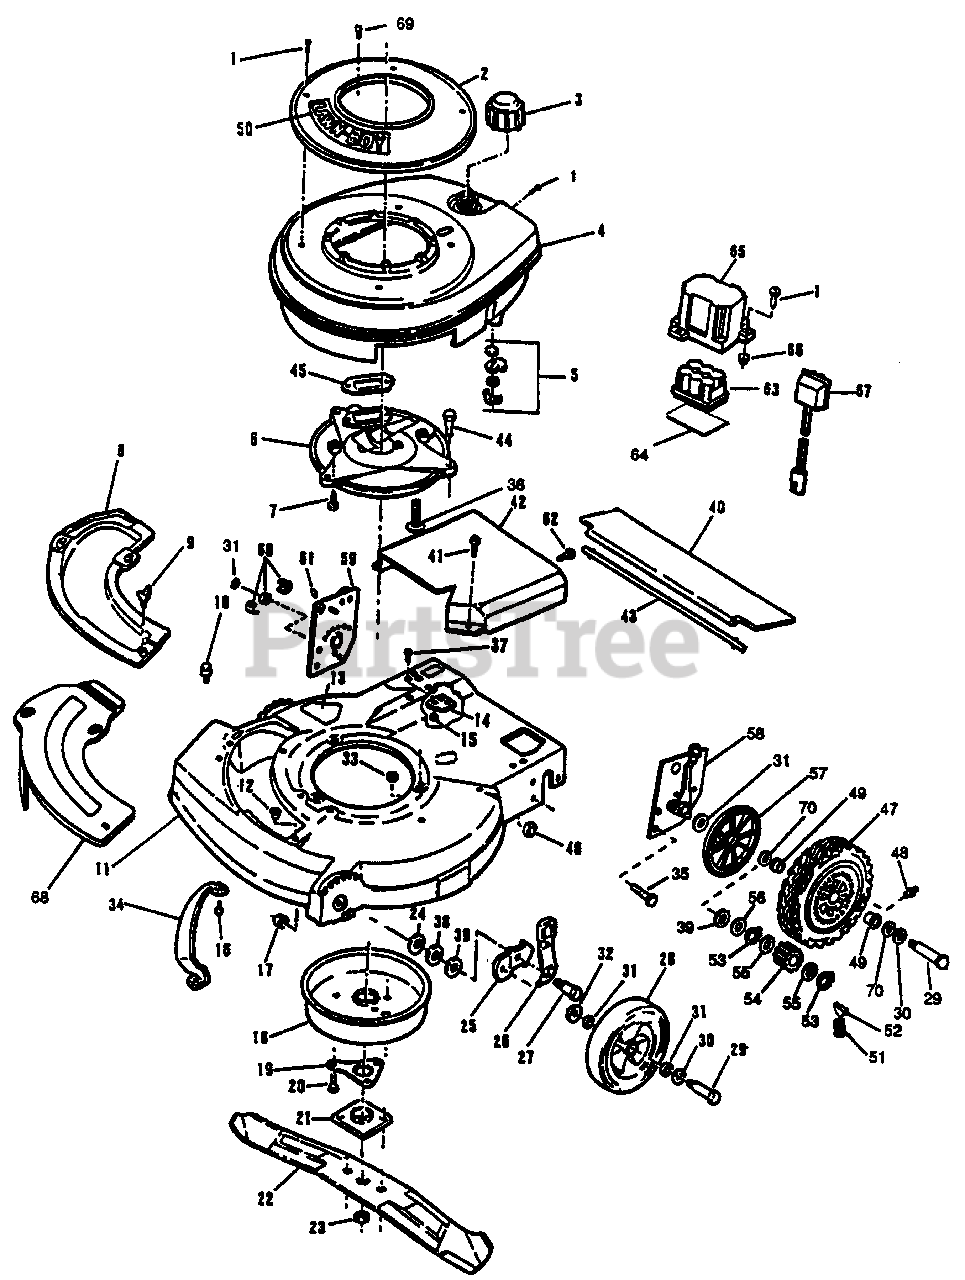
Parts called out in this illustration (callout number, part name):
1	Screw
2	Starter Base & Nut Assembly
3	Fuel Cap
4	Shroud-Engine (Inc. 5)
5	Fuel Shut-Off Assembly
6	Plate Muffler
7	Screw-Muffler Plate To Block
8	Cover Plate
9	Wing Screw
10	Screw-Plate & Chute Mounting
11	Housing Assembly (Inc. 12-13)
12	Grommet
13	Decal-Blade Contact Warning
14	Bolster-Housing
15	Nut-Bolster To Housing
16	Screw
17	Nut
18	Muffler Cover Assembly
19	Support-Crankshaft
20	Screw-Muffler To Muffler Plate
21	Collar & Plate Assembly
22	Blade-21"
23	Nut-Blade
24	Washer
25	Bracket-Wheel Height Adjust
26	Knob & Spring Assembly
27	Bolt-Shoulder
28	Wheel-Front
29	Bolt-Wheel
30	Washer-Flat
31	Washer-Felt
32	Washer
33	Nut-Muffler Plate To Housing
34	Toe Bar
35	Screw-Handle Bracket
36	Screw-Muffler Plate To Block
37	Screw Bolster To Housing
38	Washer-Shim-Wheel Height Adjust Bracket
39	Washer-Shim-Wheel Height Adjust Bracket
40	Shield-Trailing
41	Screw-Drive Cover Mounting
42	Cover-Drive
43	Rod-Trailing Shield
44	Screw-Muffler Plate To Housing
45	Gasket-Exhaust
46	Locknut-Hdl. Brkt. To Housing
47	Rear Wheel (Inc. 48-49)
48	Lube Fitting
49	Bushing-Wheel
50	Applique-Starter Base
51	Spring
52	Key
53	Retaining Ring
54	Pinion
55	Spacer
56	Washer
57	Cover-Rear Wheel
58	Height Adjuster Assembly-L.H. (Inc. 60-61)
59	Height Adjuster Assembly-R.H. (Inc. 60-61)
60	Bearing & Retainer Assembly
61	Fitting
62	Screw
63	Battery Pack Assy (Inc. 64)
64	Pad-Battery
65	Cover-Battery
66	Grommet-Battery Mounting
67	Battery Charger Assembly
68	Mulch Plate Accessory
69	Screw-Starter Mounting
70	Washer-Felt
